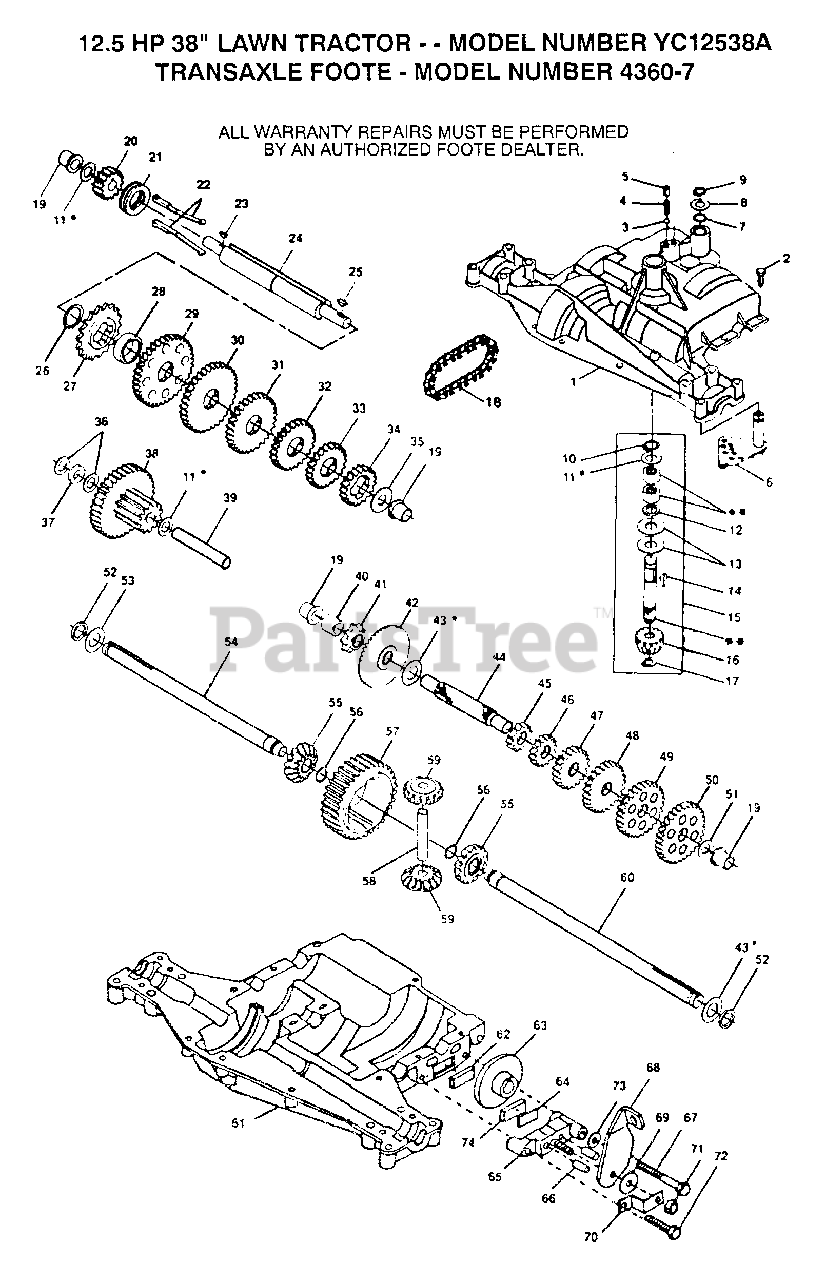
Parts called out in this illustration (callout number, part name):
1	HOUSING UPPER
3	BALL DETENT
4	SPRING, DETENT
5	SCREW, SET
6	ASSY SHIFTER
8	WASHER PLAIN
8A	WASHER PLAIN
8B	WASHER PLAIN
8C	WASHER PLAIN
8D	WASHER PLAIN
8E	WASHER PLAIN
8F	WASHER PLAIN
9	RING RETAINING
10	RING RETAINING
11	WASHER PLAIN
11A	WASHER PLAIN
11B	WASHER, PLAIN .632 X 1.00 X .026
11C	WASHER PLAIN
11D	WASHER PLAIN
11E	WASHER PLAIN
11F	WASHER PLAIN
11G	WASHER PLAIN
11H	WASHER, PLAIN .632 X 1.00 X .060
11I	WASHER PLAIN
13	WASHER, PLAIN .632 X 1.38 X .046
14	KEY WOODRUFF #9
15	ASSY KIT INPUT SHAFT
16	PINION, BEVEL, 14 TEETH
17	RING, RETAINING
18	CHAIN, 24 PITCHES
19	BEARING, FLANGE
20	GEAR SPUR, 14 TEETH
21	COLLAR CLUTCH
22	KEY CLUTCH
23	KEY WOODRUFF #3
24	SHAFT INTERMEDIATE
25	KEY, WOODRUFF, #61
26	RING, RETAINING
27	SPROCKET, 18 TEETH
29	GEAR, SPUR, 37 TEETH
30	GEAR, SPUR, 35 TEETH
31	GEAR, SPUR, 30 TEETH
32	GEAR, SPUR, 25 TEETH
33	GEAR, SPUR, 22 TEETH
35	WASHER, PLAIN .640 X 1.37 X .061
36	WASHER, PLAIN .632 X 1.00 X .026
37	SPACER .630 X 1.00 X .169
38	ASSY GEAR COMB 12&35 TEETH
39	SHAFT IDLER
40	SPACER .635 X .875 X .755
41	SPROCKET, 9 TEETH
42	GEAR, BEVEL, 42 TEETH
43	WASHER PLAIN
43A	WASHER PLAIN
43B	WASHER PLAIN
43C	WASHER PLAIN
43D	WASHER PLAIN
43E	WASHER PLAIN
43F	WASHER, PLAIN .758 X 1.25 X .031
43G	WASHER PLAIN
43H	WASHER PLAIN
43I	WASHER PLAIN
43J	WASHER PLAIN
43K	WASHER PLAIN
43L	WASHER PLAIN
44	SHAFT, DRIVE
45	GEAR, SPUR, 12 TEETH
46	GEAR SPUR, 15 TEETH
47	GEAR, SPUR, 20 TEETH
48	GEAR, SPUR, 25 TEETH
49	GEAR, SPUR, 28 TEETH
50	GEAR, SPUR, 31 TEETH
51	WASHER, PLAIN .632 X 1.00 X .060
53	WASHER PLAIN
54	AXLE LEFT HAND
55	GEAR, MITER, 15 TEETH
56	RING, RETAINING
57	GEAR, SPUR, 32 TEETH
58	SHAFT, CROSS
59	GEAR, MITER, 15 TEETH
60	AXLE, R.H.
61	HOUSING LOWER
62	PUCK, FRICTION
63	DISC, BRAKE
65	JAW, BRAKE
66	PIN, DOWEL
67	SCREW TAPPING
68	LEVER, ACTUATING
69	WASHER, PLAIN .321 X 1.00 X .055
70	BRACKET, ANTI-ROTATION
71	LOCKNUT 5/16-24
72	SCREW TAPPING
73	WASHER PLAIN
74	PUCK, FRICTION
